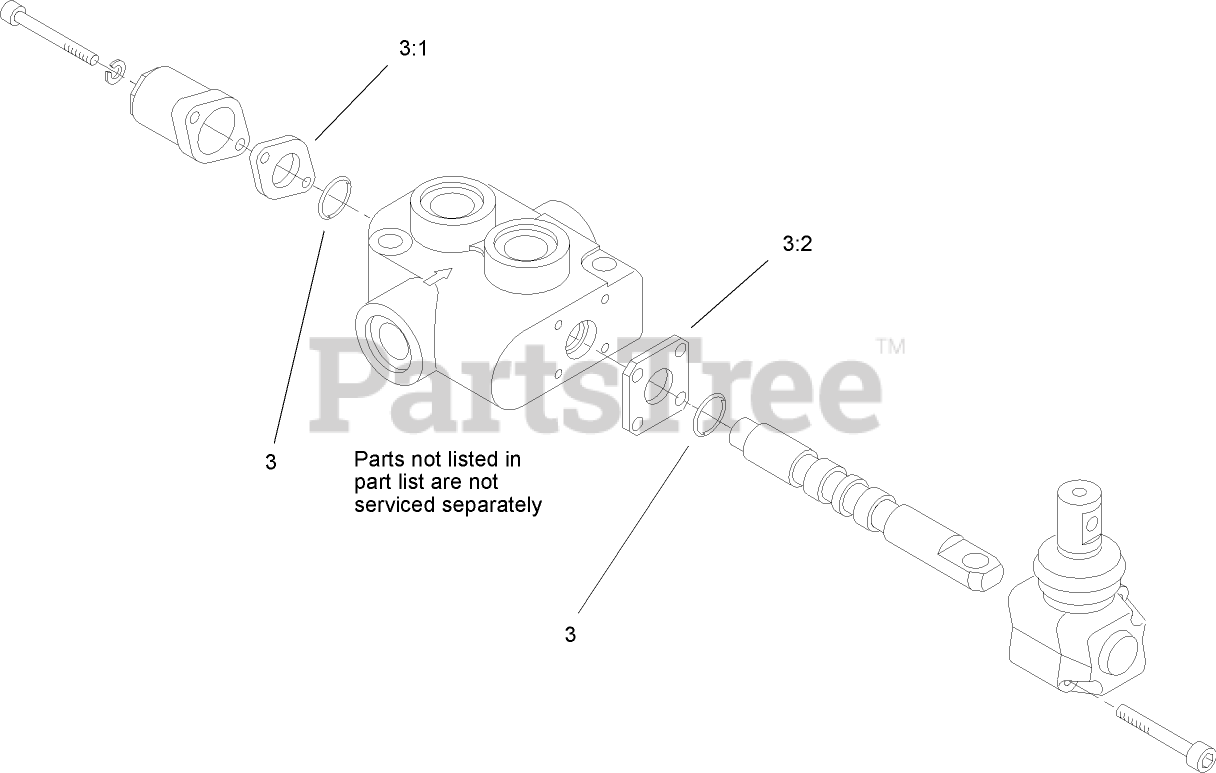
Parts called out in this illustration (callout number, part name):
3	SEAL KIT
3:1	GASKET
3:2	GASKET
